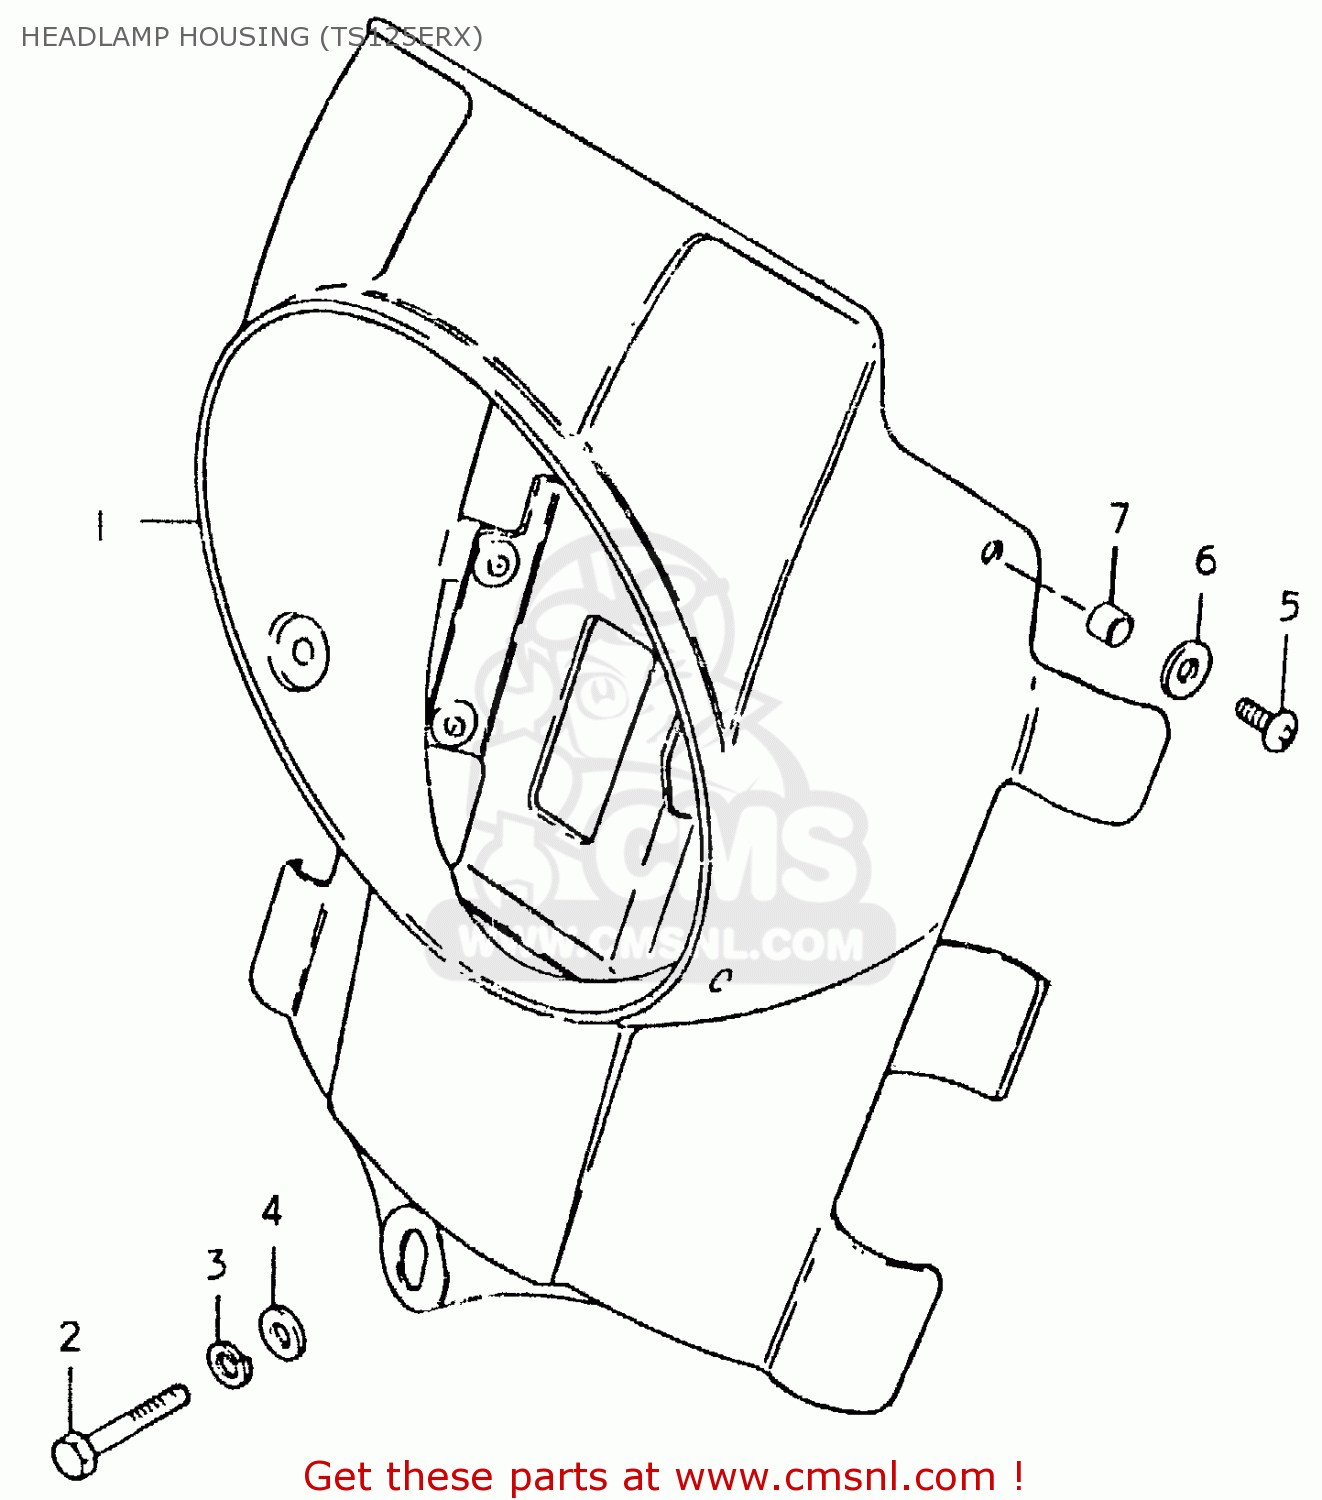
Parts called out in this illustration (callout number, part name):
1	HOUSING,HEADLAMP
2	BOLT
3	LOCK WASHER
4	WASHER
5	SCREW
6	WASHER (5.5X18X1.6)
7	SPACER (5.5X8X4)
